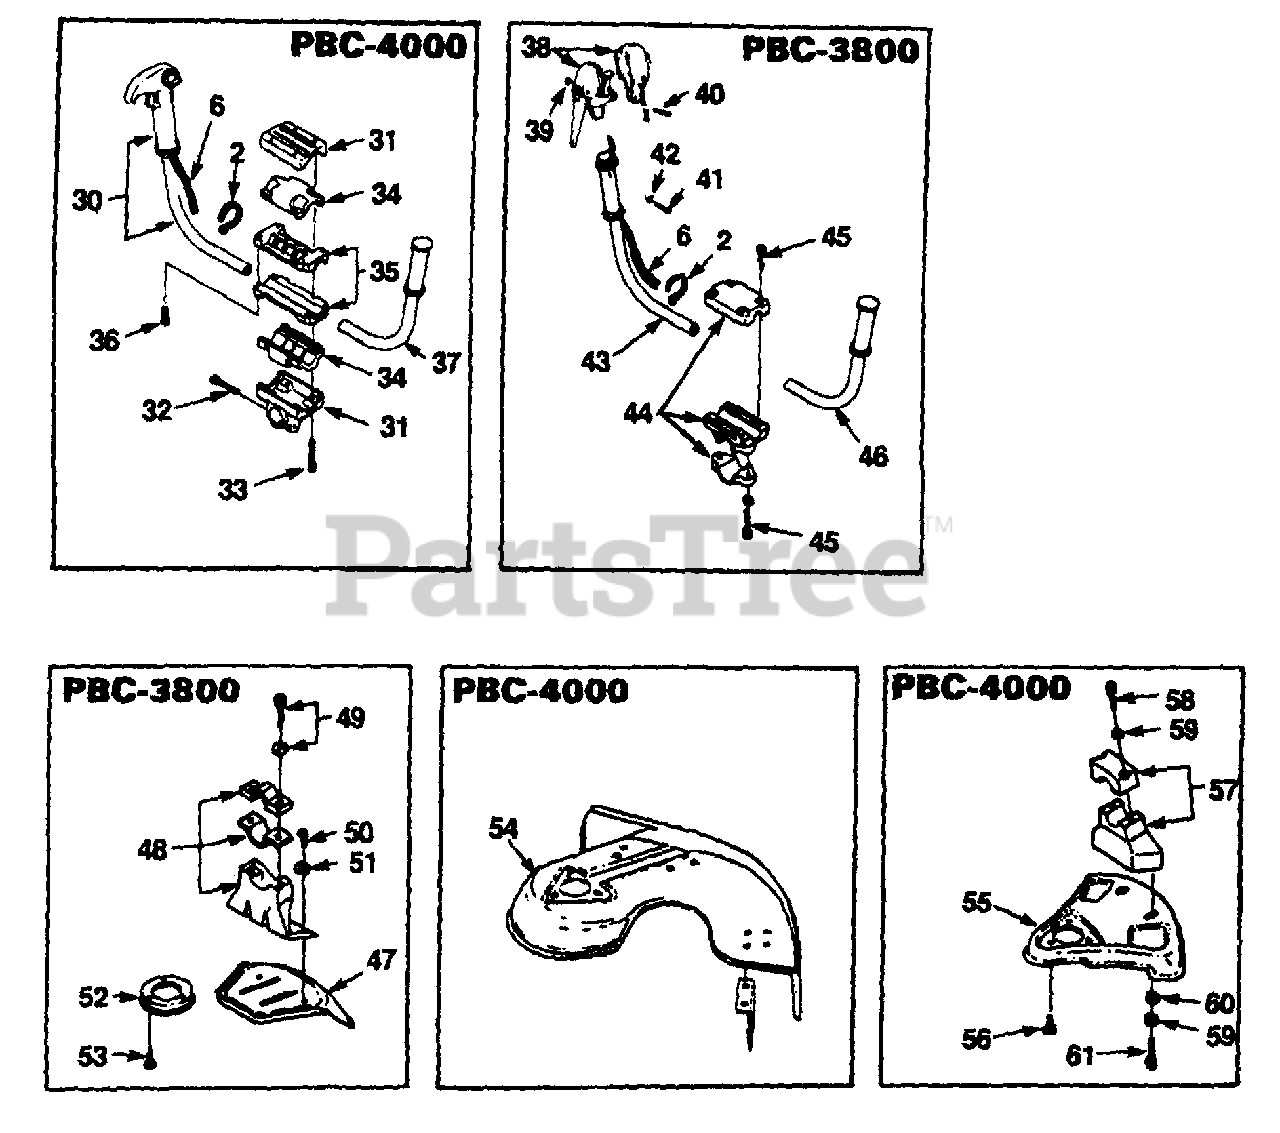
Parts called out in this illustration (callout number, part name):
30	HANDLE BAR & THROTTLE (R.H.)
31	HOUSING ASSEMBLY
32	SCREW-Socket (M5 X 30)
33	SCREW-Machine (M5 X 40)
34	JOINT-Rubber
35	CAST JOINT ASSEMBLY
36	SCREW-Socket (M5 X 25)
37	HANDLE BAR-Left
38	THROTTLE & SWITCH
39	NUT-Hex
40	SCREW-Pan Hd. (M4 X 25)
41	SCREW-Thread Form. (6 X 3/8")
42	WASHER-Lock
43	HANDLE BAR-Right
44	BRACKET-Handle Bar
45	SCREW & WASHER
46	HANDLE BAR-Left
47	GRASS SHIELD
48	DEFLECTOR-Bracket Kit
49	SCREW & WASHER (Socket Hd.)
50	SCREW-Machine (6MM)
51	WASHER-Flat
52	RING-Grass Shield
53	SCREW-Machine Hex (M5 X 10)
54	GRASS DEFLECTOR KIT
55	GUARD-Blade (10")
56	SCREW-Machine Hex Sems (M5 X 10)
57	GUARD-Stand
58	SCREW-Socket Hd. (M5 X 25)
59	WASHER-Lock (M6)
60	WASHER-Flat (M6)
61	SCREW-Socket Hd. (M6 X 12)
